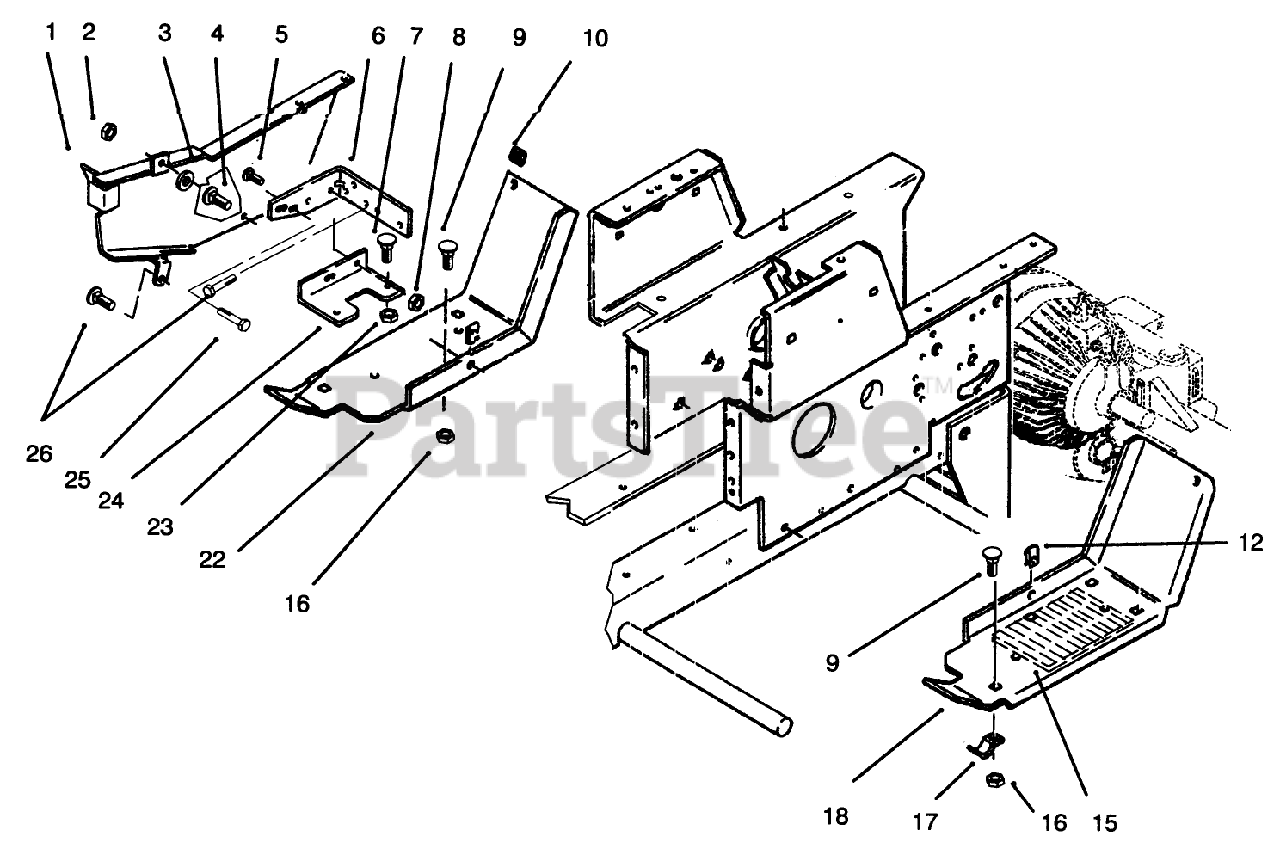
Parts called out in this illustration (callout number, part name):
1	GUARD - BELT WA *R
2	NUT-LOCK, NI
4	SCREW-PPH
5	SCREW-HH
6	BRACKET-BELT*B
7	SCREW-PAN
8	NUT-LOCK, NI
9	BOLT-CARR
10	BUMPER
15	PAD FOOTREST
16	NUT-LOCK, NI
17	BRACKET
18	FOOTREST LH *R
24	BRKT-FUS HLDER*B
25	BOLT-CARR
